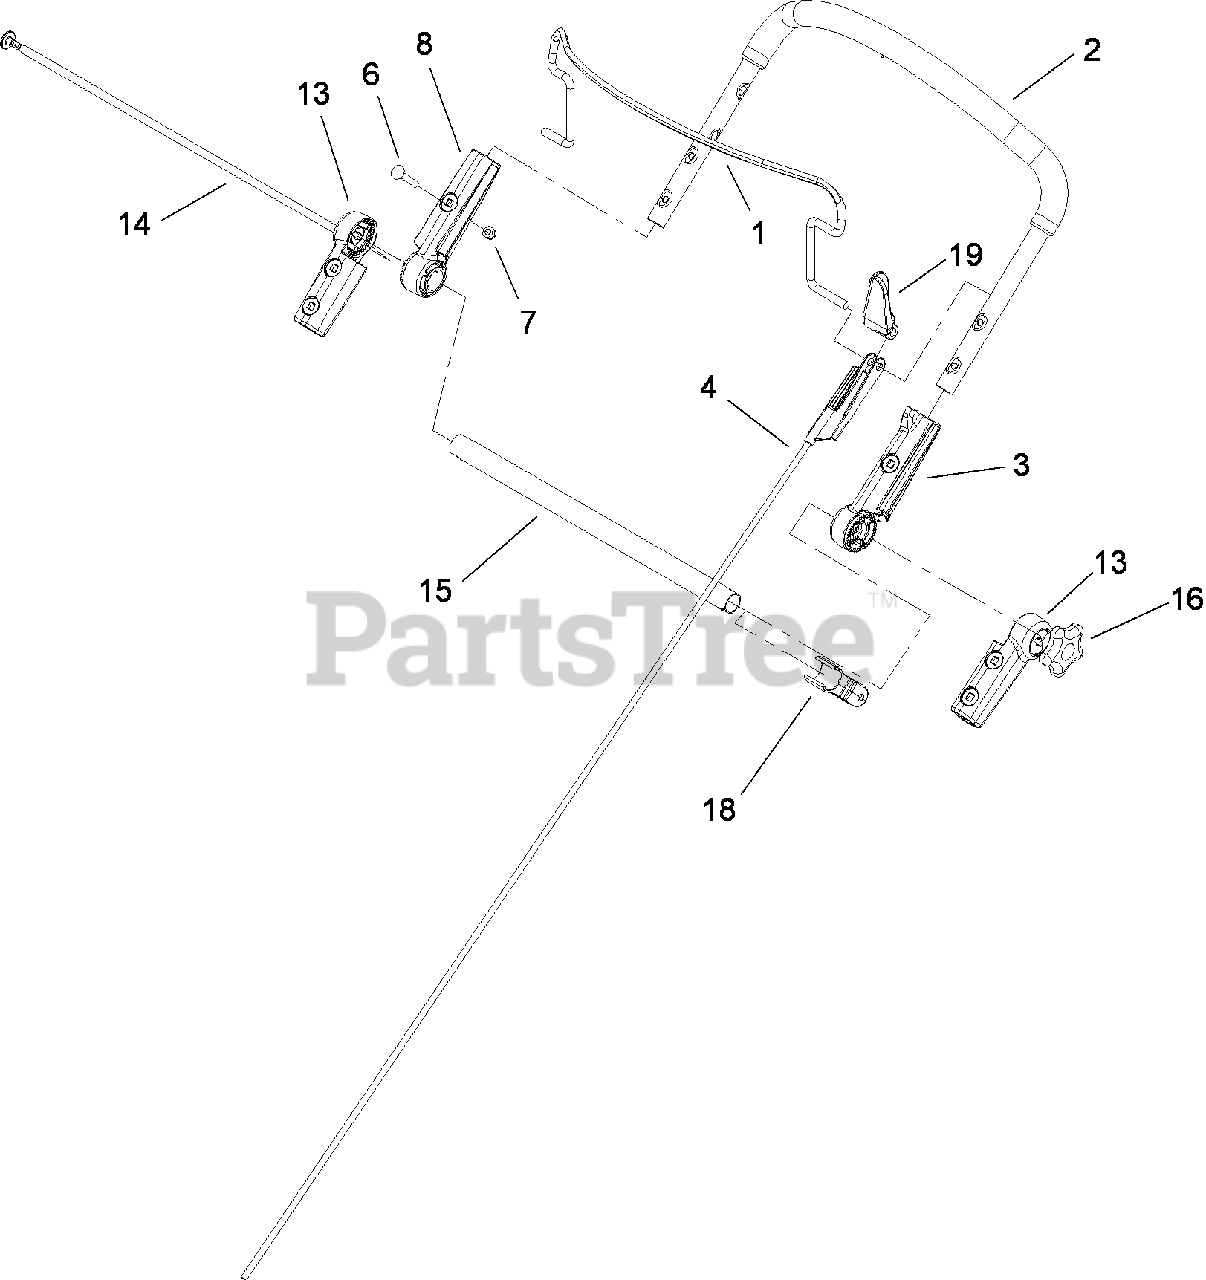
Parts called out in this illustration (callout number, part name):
2	HANDLE ASM
3	MOUNT-HANDLE, LH
4	CABLE-BRAKE
6	SCREW-CARR
7	NUT-LOCK, NI
8	MOUNT-HANDLE, RH
13	MOUNT-HANDLE, LOWER
14	ROD-THREADED
18	CLAMP-CABLE
19	STOP-PIVOT
